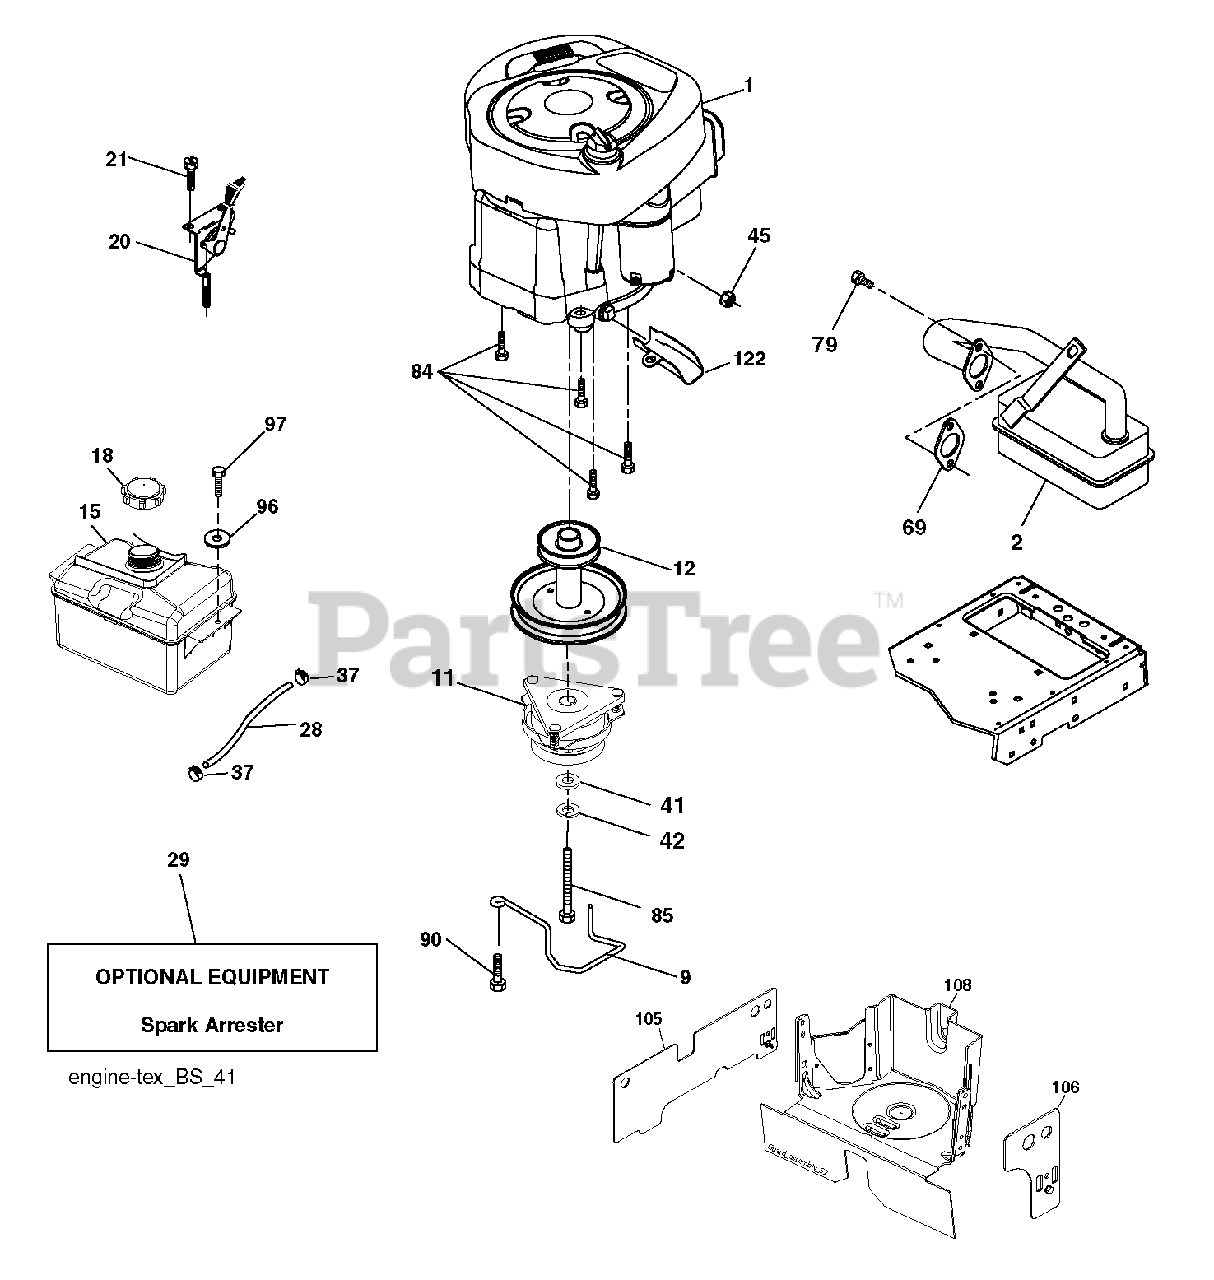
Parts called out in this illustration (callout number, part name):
9	KEEPER.BELT.ENGINE.3.25
11	CLUTCH
12	PULLEY.ASM.ENG.OGURA.3
15	TANK FUEL FRT 1.5 GAL
18	CAP ASM.FUEL.2.25"FR.
20	CONTROL.TH/CK.C.
21	SCREW.#10 X 0.750.BOS THREAD
28	LINE.FUEL.20
29	ARRESTER SPARK (OPTIONAL)
37	HOSE CLAMP
42	LOCKWASHER
45	NUT
69	REPL BY 532 27 22-93
79	SCREW.SOCKET HD.5/16-1
84	SCREW.3/8-16
85	BOLT HEX 7/16-20X4-1/4"
90	SCREW 3/8-16X1
97	SCREW HEXWSHR 1/4-20X3/4
122	EXTENSION DRAIN OIL
